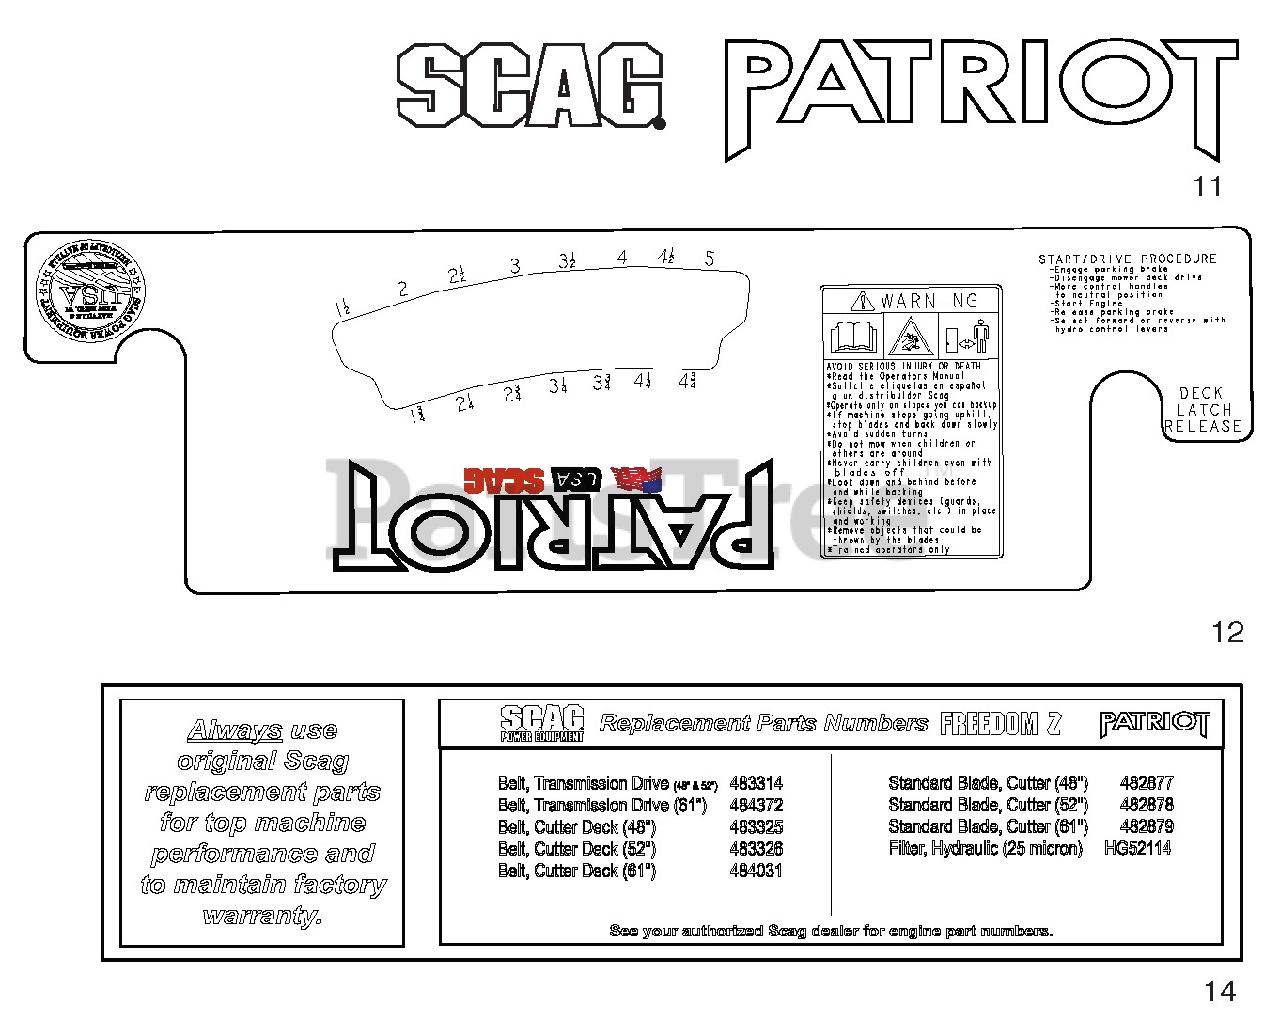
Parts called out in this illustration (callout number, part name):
11	Decal, Front SPZ
12	Decal, Cutting Height - SPZ
14	Decal, SFZ / SPZ Replacement Parts
